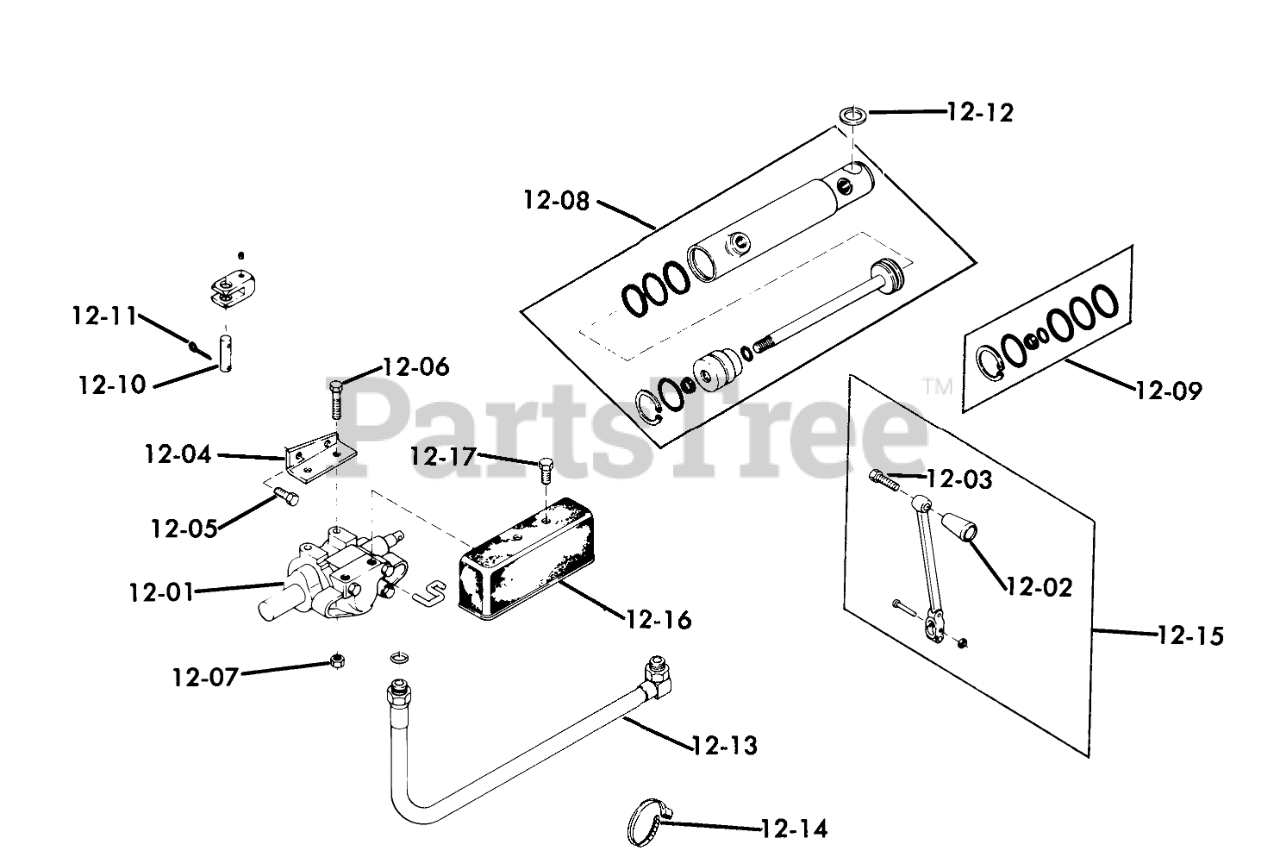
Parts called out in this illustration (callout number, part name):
12-01	Valve
12-01	Ring Kit
12-01	Spool Cap Kit
12-03	SCREW
12-04	SUPPORT-VALVE
12-05	Bolt
12-06	Bolt 1/4-20 X 1 1/2
12-07	Nut
12-08	CYLINDER ASSY R
12-09	S/A O-RING&GASKET AS
12-10	PIN
12-12	Spacer
12-13	16" Hose Assembly
12-14	PLASTIC TIE
12-15	Assy-Handle
12-16	Cover-Valve
12-17	Bolt
